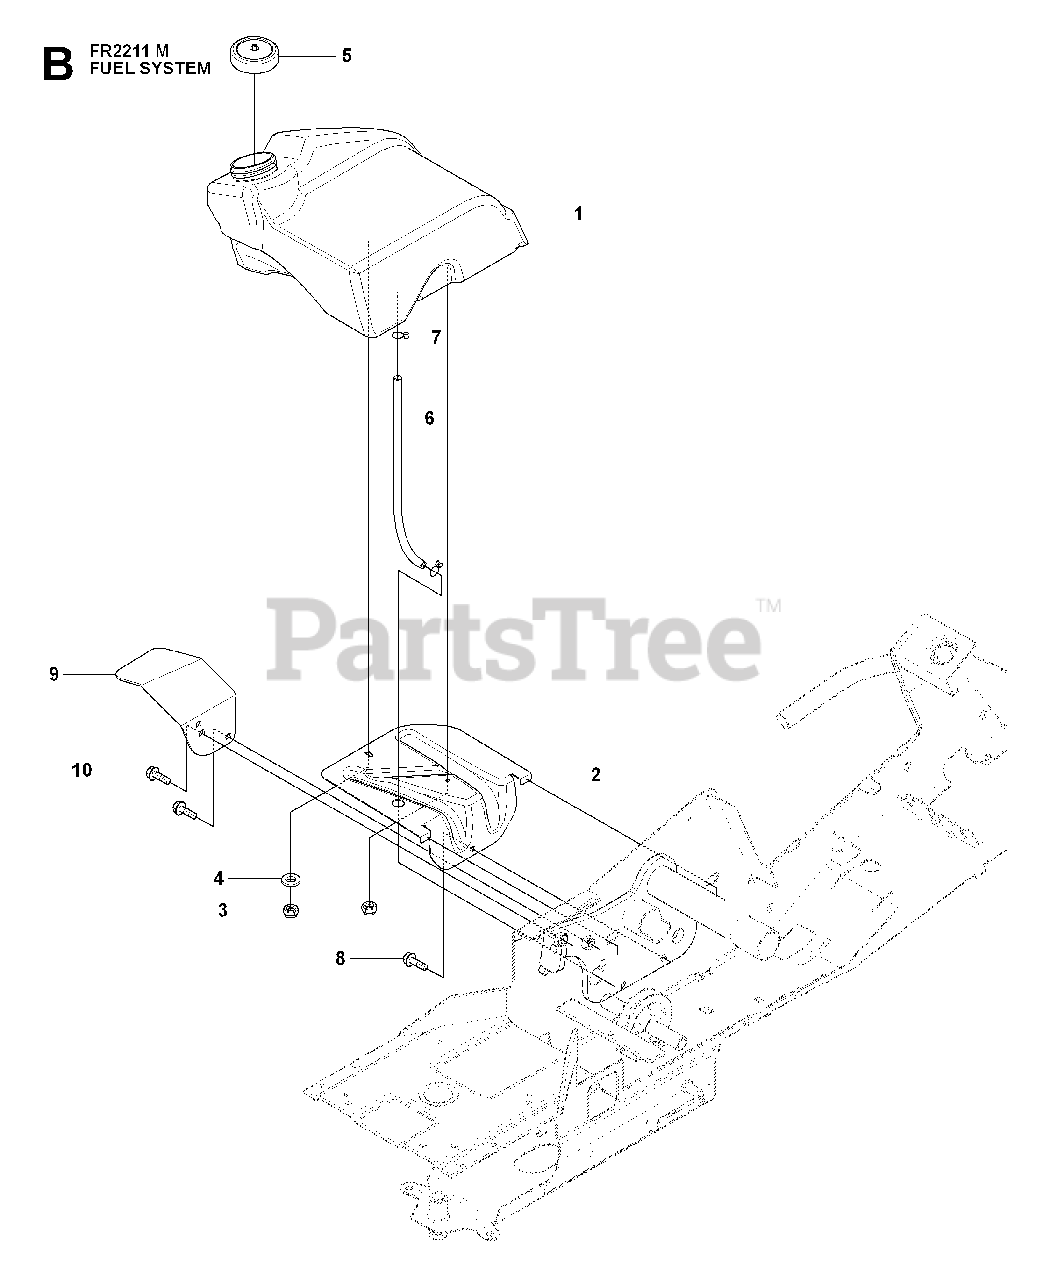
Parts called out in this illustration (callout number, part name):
3	LOCKNUT M6
4	WASHER
10	SCREW M10X25
